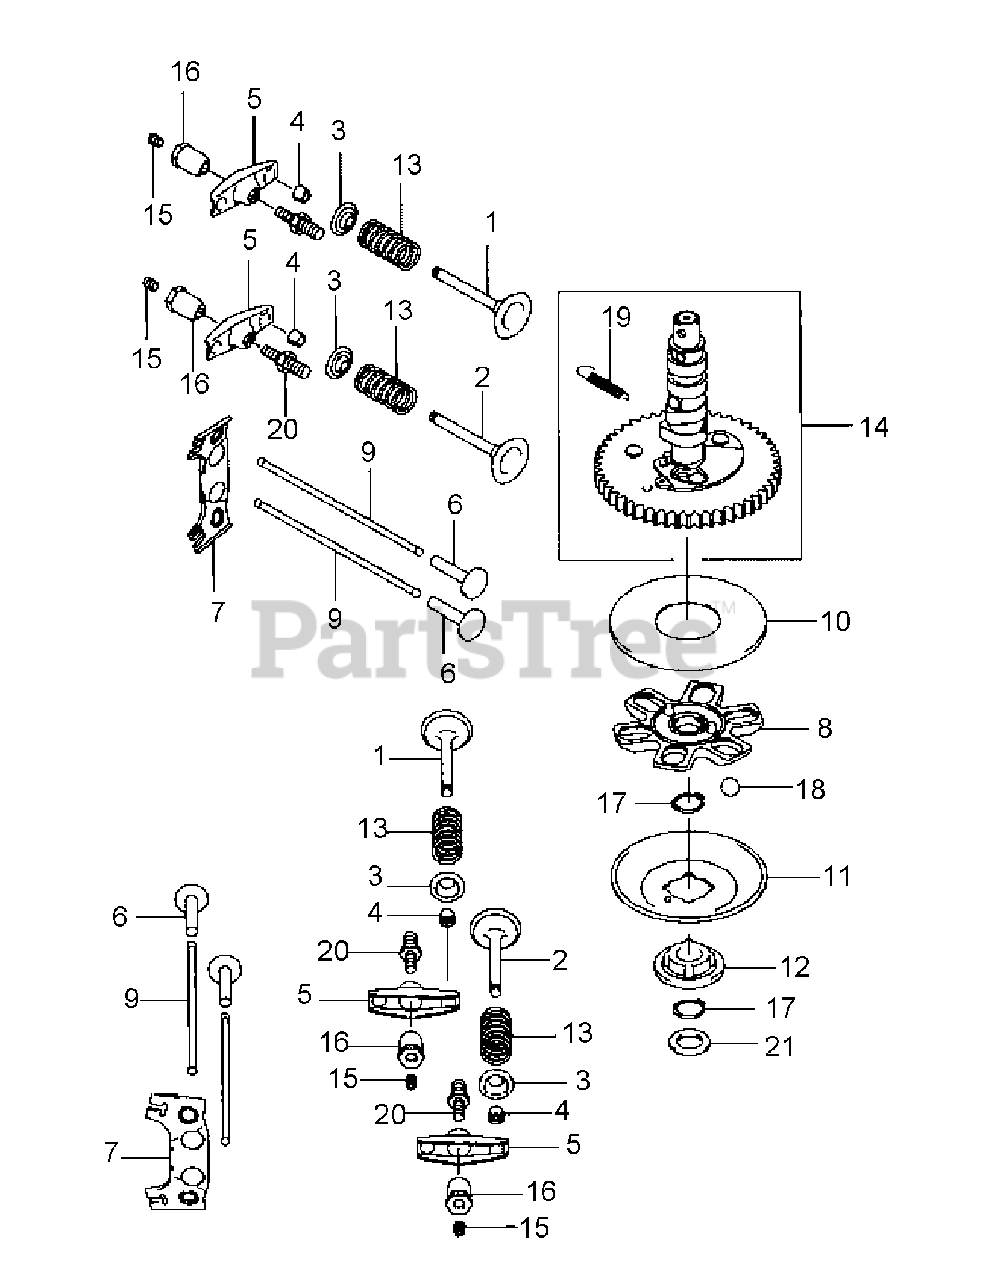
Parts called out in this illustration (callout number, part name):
1	VALVE-INTAKE
2	VALVE-EXHAUST
3	RETAINER-VALVE SPRING
11	PLATE, GOVERNOR
13	SPRING-ENGINE VALVE
14	CAMSHAFT-COMP
17	RING-SNAP
18	BALL
19	SPRING
